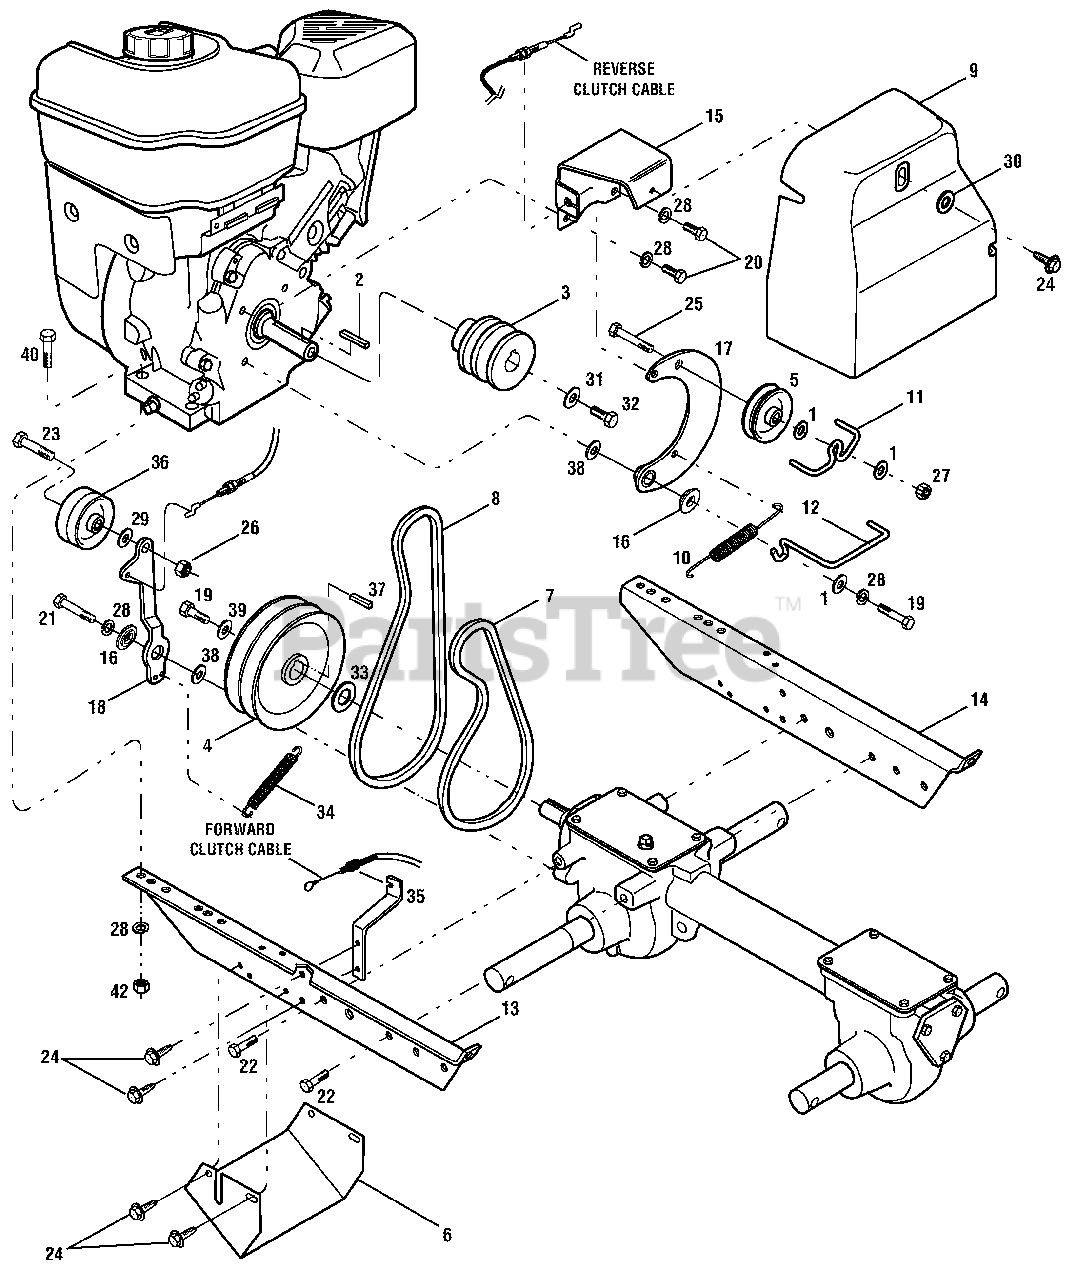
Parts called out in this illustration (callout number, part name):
1	Flat Washer, 5/16
2	Key, 3/16" x 1-1/2"
3	Pulley, Engine Drive
4	Transmission Pulley
5	Pulley, Reverse Idler
6	Guard, Belts/Pulleys
7	Forward Drive Belt
8	Reverse Drive Belt
9	Belt Cover
10	Reverse Return Spring
11	Belt Guide
12	Forward Belt Guide
13	Engine Bracket, Left
14	Engine Bracket, Right
15	Bracket, Belt Cover
16	Shoulder Washer
17	Reverse Idler Arm
18	Forward Idler Lever
19	Hex Hd. Screw, 5/16-24 x 1
20	Hex Hd. Screw, 5/16-24 x 5/8
21	Hex Hd. Screw, 5/16-18 x 1
22	Hex Hd. Screw, 5/16-18 x 5/8
23	Hex Hd. Screw, 3/8-16 x 1-1/2
24	Screw, Self-Tapping, 1/4-20 x 1/2
25	Hex Hd. Screw, 5/16-18 x 2
26	Lock Nut, 3/8-16
27	Lock Nut, 5/16-18
28	Lock Washer, 5/16
29	Flat Washer, 3/8
30	Flat Washer
31	Bell Washer
32	Hex Hd. Screw, 3/8-24 x 1.5, GR5
33	Support Washer
34	Forward Return Spring
35	Bracket, Cable Mounting
36	Forward Idler Pulley
37	Key, 3/16" x 1"
38	Flat Washer
39	Belleville Washer
40	Hex Screw, 5/16-18 x 2.25 Gr5
